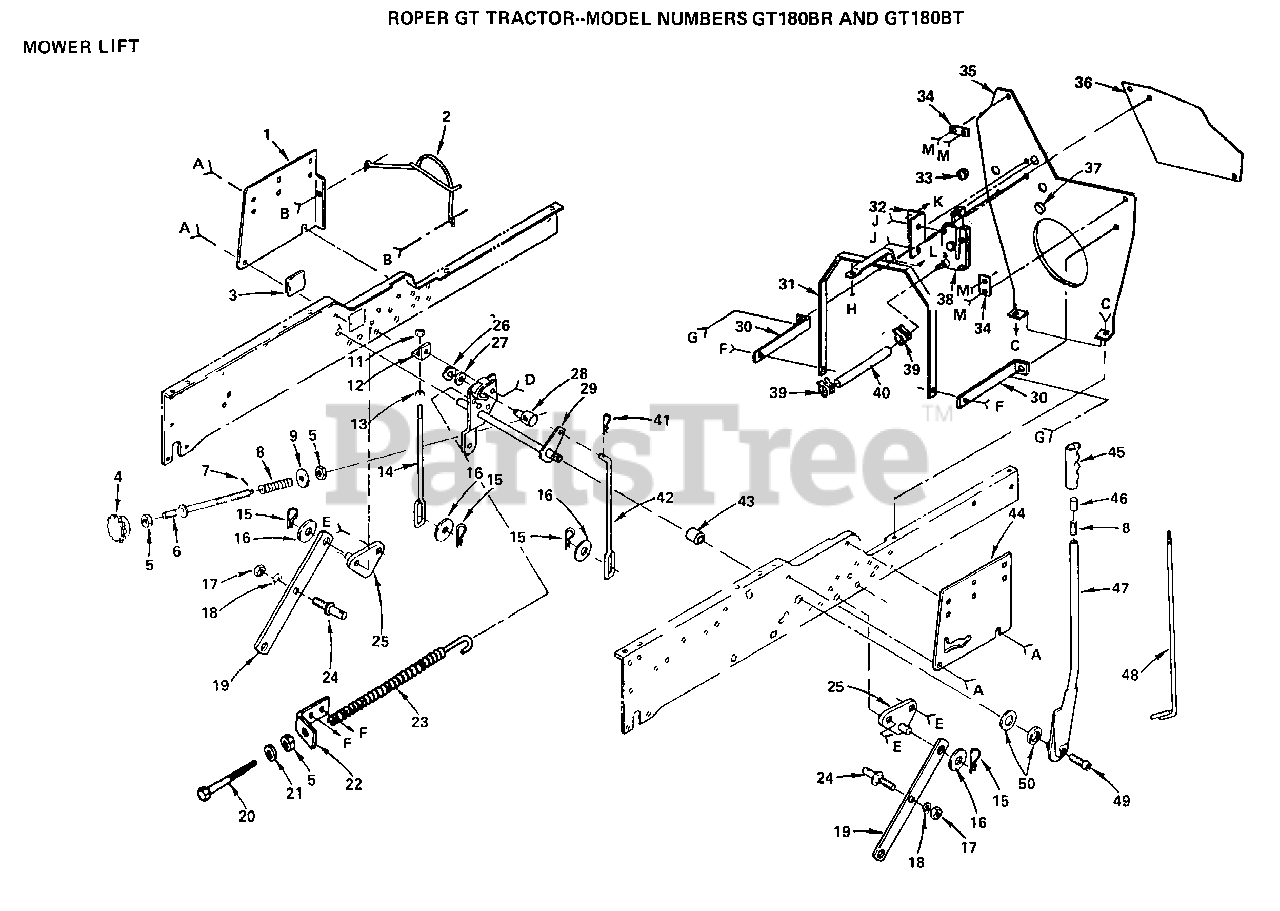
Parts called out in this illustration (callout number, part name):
2	ENGINE BELT GUARD
5	NUT
8	SPRING T
9	WASHER
11	NUT
12	BRACKET T
13	NUT.HEX.3/8-16UNC
14	LINK-LIFT MOW T
15	SPRING H
17	NUT
18	LOCKWASHER
19	SUSPENSION ARM GT
20	BOLT-ADJ SPRING T
25	PIVOT STUD GT
25	SUSP BRACKET T
26	KLIP RING
27	WASHER
28	TRUNION T
29	LIFT SHAFT GT
30	BRKT-SHIELD, HEAT, SIDE
33	SNAP BUSHING T
36	PANEL-SHIELD, HEAT
37	PLUG GT
42	LIFT LINK RH T
49	SCREW LT
